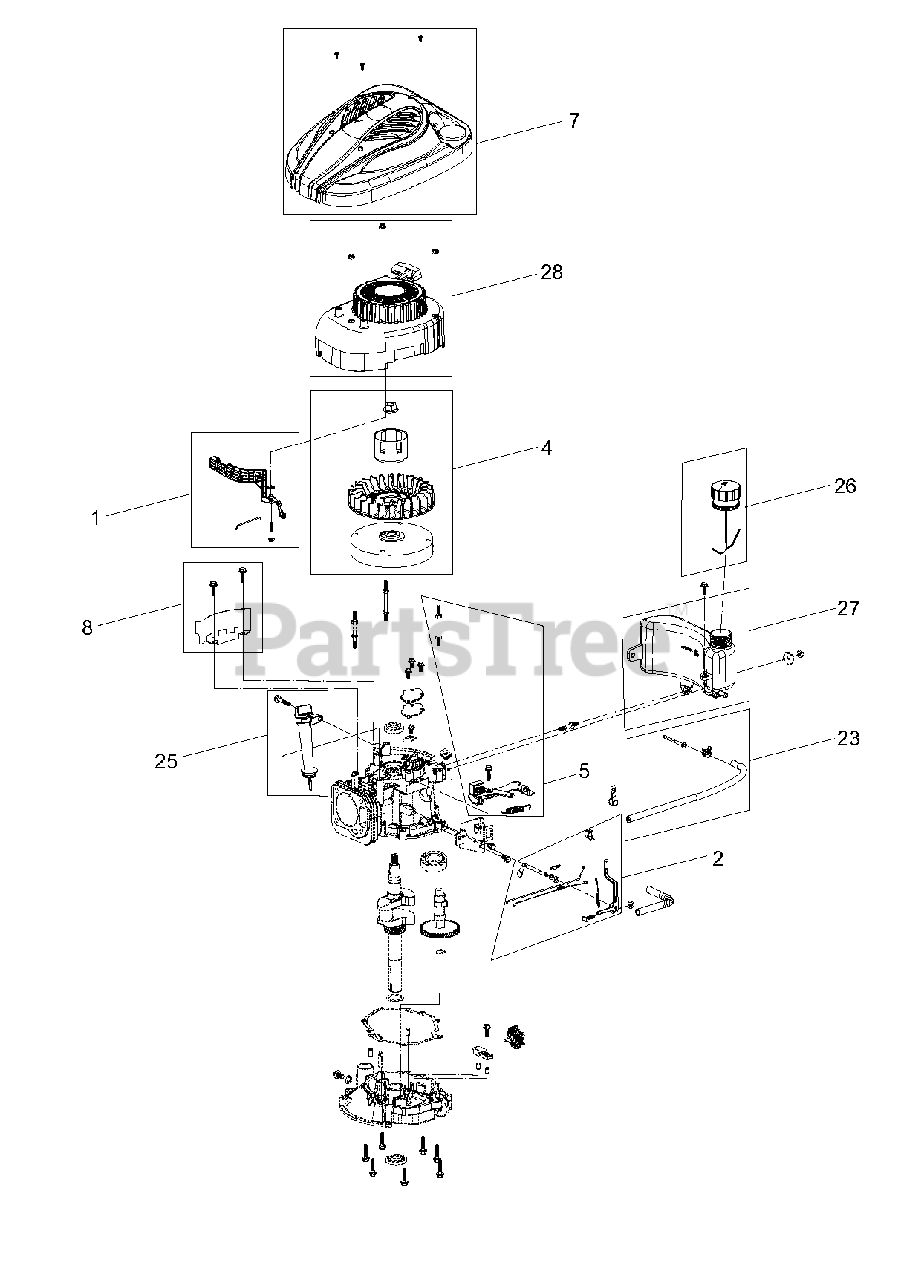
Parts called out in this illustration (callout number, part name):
1	AIR VANE CHOKE KIT
2	GOVERNOR ARM KIT
3	MUFFLER AND SHIELD KIT
4	FLYWHEEL AND FAN KIT – RECOIL START
5	KIT BRAKE ASSEMBLY RECOIL
7	KIT ARIENS STYLE
8	KIT FLYWHEEL SHIELD
9	THERMAL CHOKE CONTROL KIT
10	KIT-AIR CLEANER ASM, 2 HINGE
11	CARBURETOR COMPLETE KIT
12	IGNITION COIL KIT
18	KIT-VALVE COVER (1P65FA)
19	LOCK-THROTTLE
20	STUD-INTAKE
21	AIR FILTER, FOAM PRE-FILTER
22	AIR FILTER ELEMENT
23	FUEL LINE WITH STRAINER
24	SPARK PLUG
25	OIL FILTER TUBE/CAP
26	GAS CAP WITH CANISTER
27	FUEL TANK
28	RECOIL ASSEMBLY
